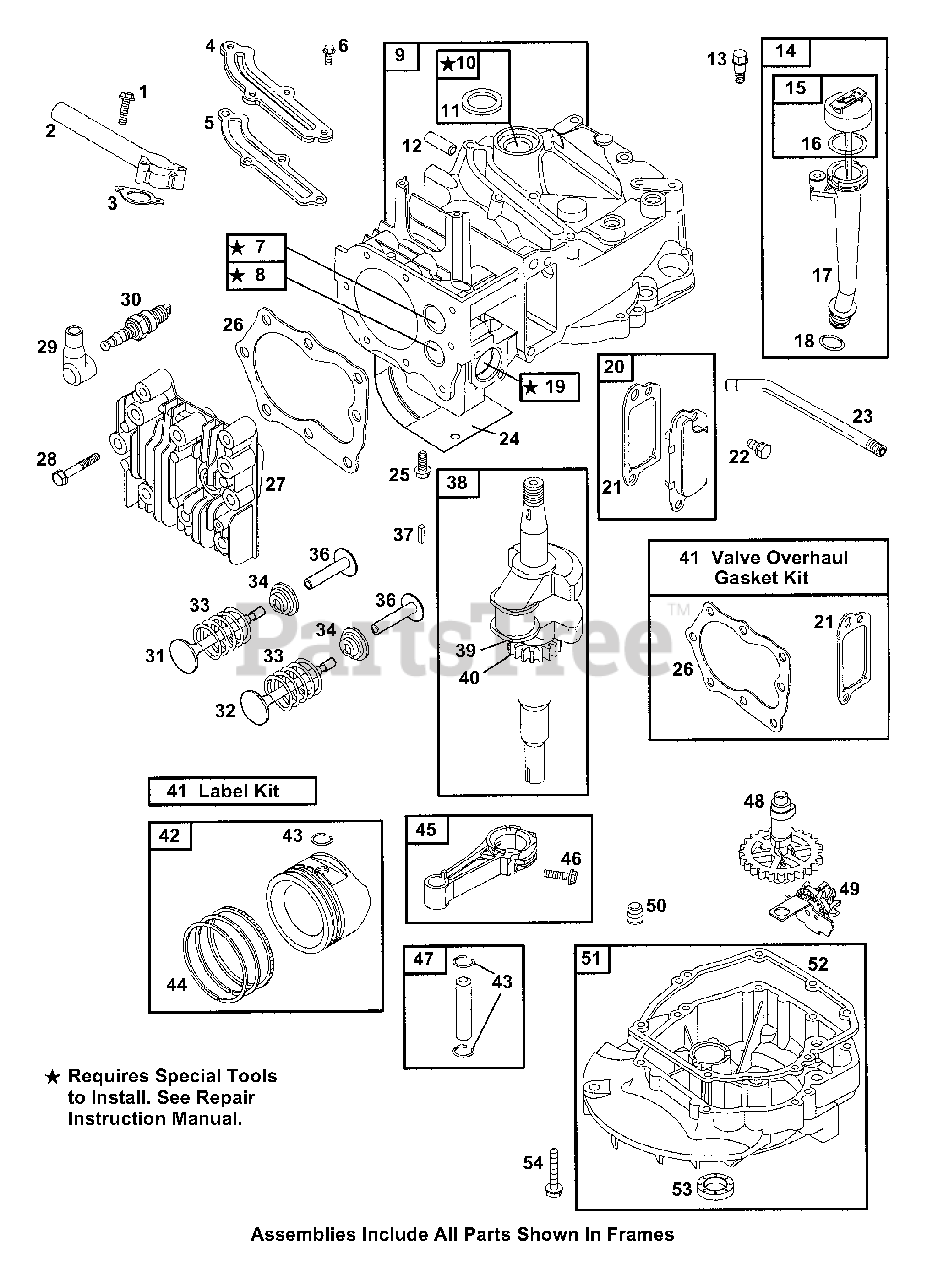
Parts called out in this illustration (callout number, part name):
1	Screw (Intake Manifold)
2	Intake Manifold
3	Intake Gasket
4	Breather Passage Cover
5	Breather Passage Gasket
6	Screw (Breather Passage Cover)
7	Valve Seat (Intake)
8	Valve Seat (Exhaust)
9	Cylinder Assembly
10	Bushing/Seal Kit
11	Oil Seal
12	Locating Pin
13	Screw (Dipstick Tube)
14	Order Component Part
15	Dipstick
16	Dipstick/Tube Seal
17	Oil Fill Tube
18	Dipstick Tube Seal
19	Guide Bushing (Intake Valve)
20	Breather Assembly
21	Breather Gasket
22	Screw (Breather Assembly)
23	Breather Tube
24	Cylinder Shield
25	Screw (Cylinder Shield)
26	Cylinder Head Gasket
27	Cylinder Head
28	Screw (Cylinder Head)
29	Sparkplug Boot
30	Spark Plug
31	Intake Valve
32	Exhaust Valve
33	Valve Spring
34	Valve Retainer
36	Valve Tappet
37	Flywheel Key
38	Crankshaft
39	Timing Key
40	Timing Gear
41	Valve Overhaul Gasket Set
42	Piston Assembly (Standard)
43	Piston Pin Lock
44	Ring Set (Standard)
45	Connecting Rod
46	Screw (Connecting Rod)
47	Piston Pin
49	Governor/Oil Slinger
50	Oil Drain Plug
51	Engine Sump
52	Crankcase Gasket
53	Oil Seal
54	Screw (Engine Sump)
